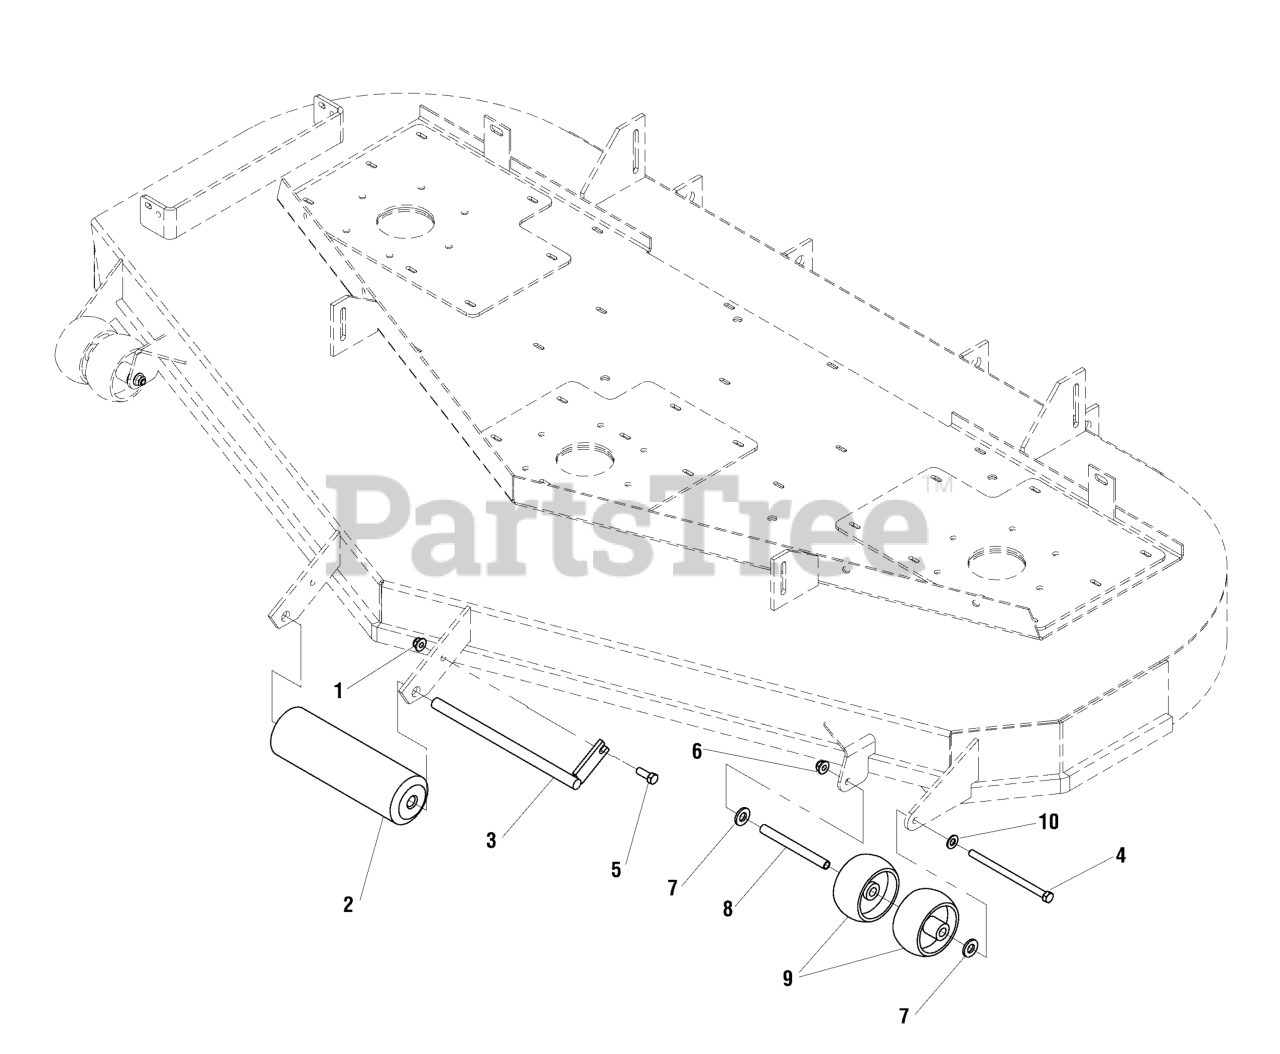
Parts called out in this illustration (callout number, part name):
1	NUT, 5/16-18 HEX NYLOCK FLANGE
2	ROLLER, DECK
4	BOLT, 3/8-16 X 6" GD5 CZ
5	BOLT, 5/16-18 X 3/4 GD5
6	NUT, 3/8-16 HEX NYLOCK FLANGE
7	WASHER, 1/2 GD9 YZ
8	SPACER, .38 X .50 X 5.06
9	WHEEL - 2.00 WIDE 3.92 DIA 0.531ID POLY
10	WASHER, 3/8 SAE
